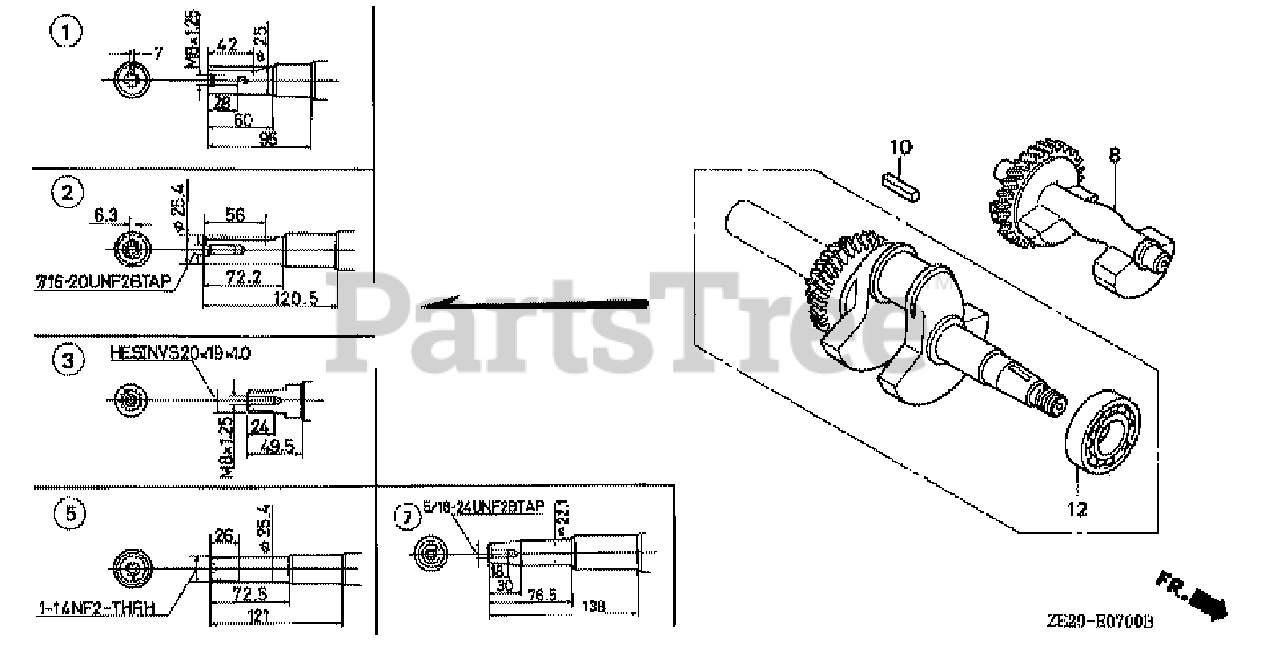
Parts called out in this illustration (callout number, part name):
2	CRANKSHAFT (Q-TYPE)
8	WEIGHT, BALANCER
10	KEY (6.3X6.3X43)
12	BEARING, RADIAL BALL (6206)
